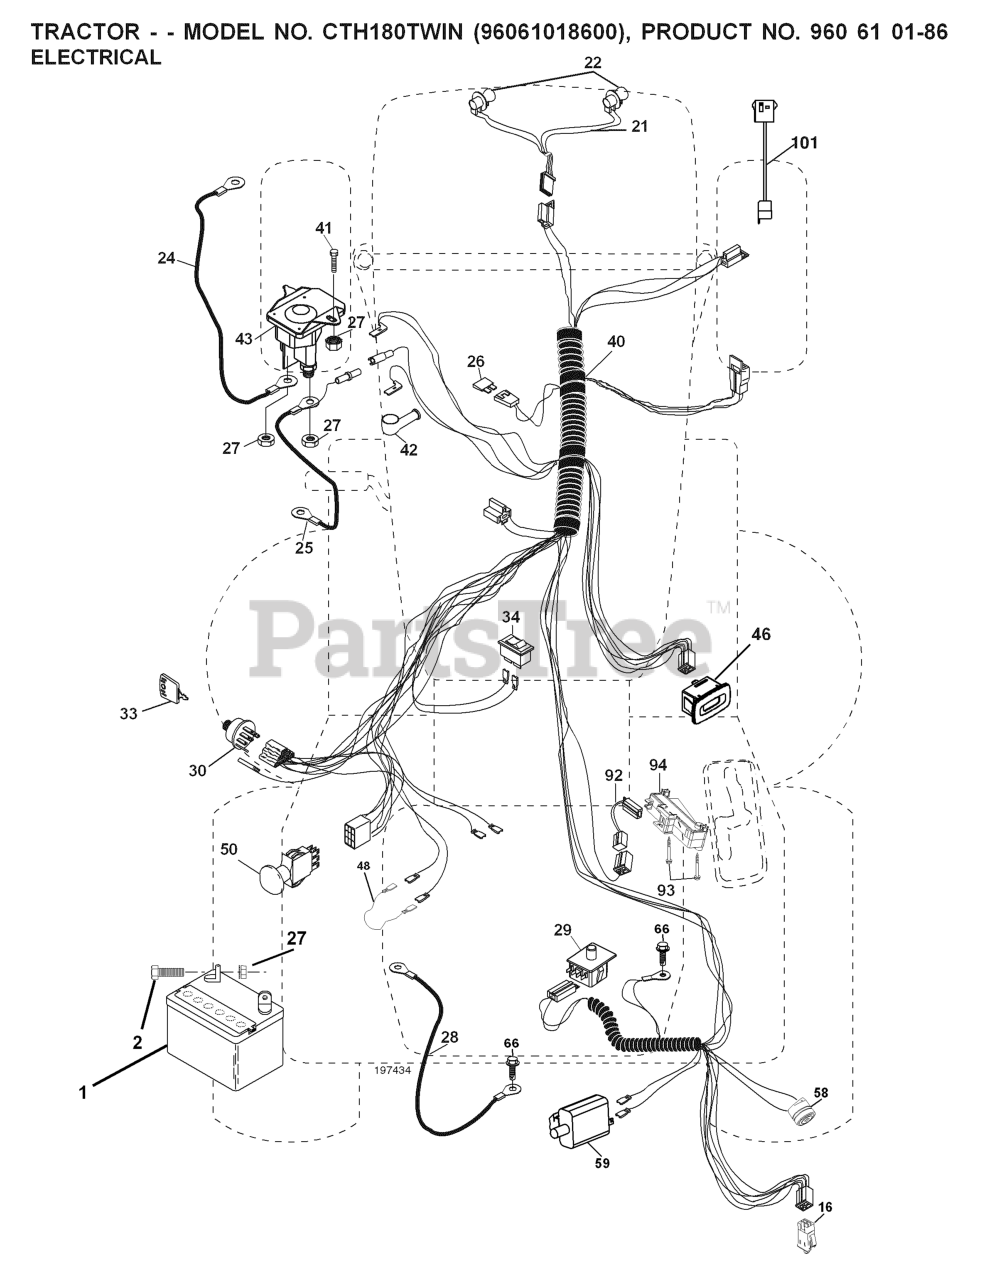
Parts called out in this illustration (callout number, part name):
1	BATTERY 12V .35 AMP
2	BOLT.HEX.1/4.X.3/4.DICHROMATE
16	SWITCH INTERLOOK PUSH-IN
21	HARNESS ASSY LIGHT
24	BATTERY CABLE GT
25	CABLE BATTERY
26	FUSE 20AMP
27	NUT
28	CABLE GROUND
29	SWITCH.SEAT.DP W/RAMPS
30	SWITCH.IGN.DELTA.W.LGH.ROS
33	KEY MLD GEN DELTA
40	RP HARNESS.IGN.ELECT.REG.CRD
41	BOLT
42	TERMINAL COVER
43	SOLENOID.W/BRASS.PLUNGER
46	RP.GUAGE.SRVCMNDR.HRMTR.
48	ADAPTER.AMMETER
50	RP.PTO.SWITCH.8 TERMINAL.BLACK
58	BUZZER
59	.WITCH.FULL BAGGER.INDICATOR
81	RELAY.ASSY.T
92	HARNESS.PIGTAIL.CONSLE
93	SCREW.PLASTITE
94	MODULE.REVERSE.ROS
101	PIGTAIL.MATNLK.NEW.HAR
